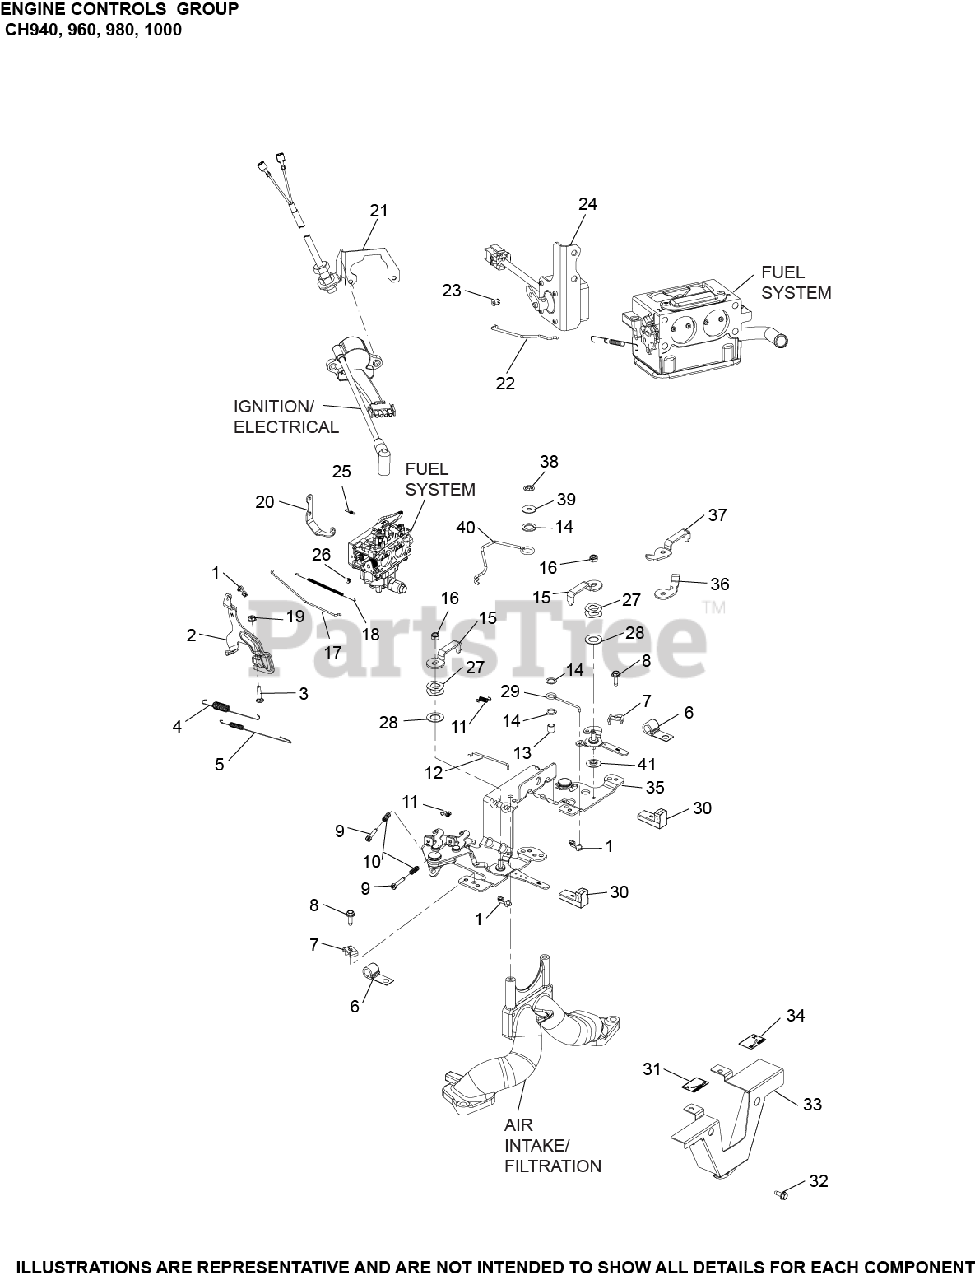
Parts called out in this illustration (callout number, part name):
1	BUSHING, THROTTLE LINKAGE
2	KIT, GOVERNOR LEVER USE 62 090 29-S
3	BOLT, RD HD SQ NECK M6X1.0X25
4	SPRING, GOVERNOR IDLE
5	SPRING, GOVERNOR
8	SCREW, THREAD FORMING
9	SCREW, PHL THD FRM M4X0.7X25
11	SPRING, RETURN
12	LINKAGE, THROTTLE LEVER
14	WASHER, NYLON
16	NUT, LOCK M6X1.0
17	LINKAGE, THROTTLE
18	SPRING, LINKAGE
19	NUT, FLG M6X1.0
20	BRACKET, CHOKE ASSIST
25	SPRING, CHOKE ASSIST
26	BUSHING, LINKAGE RETAINING
27	WASHER, SPRING
29	LINKAGE, CONTROL
30	KNOB, CONTROL LEVER
31	DECAL, THROTTLE
32	SCREW,FLG THD FRM M6X1.0X16-(#25086397S)
33	PANEL, CONTROL
34	DECAL, CHOKE
35	CONTROL ASSEMBLY, SPEED (HORIZONTAL)
36	BRACKET, MANUAL CHOKE CONTROL
37	BRACKET,MANUAL THROTTLE CONTROL
38	RETAINER, PALNUT
39	WASHER, STEEL
40	LINKAGE, CHOKE HORIZONTAL
41	WASHER, NYLON SHOULDER
